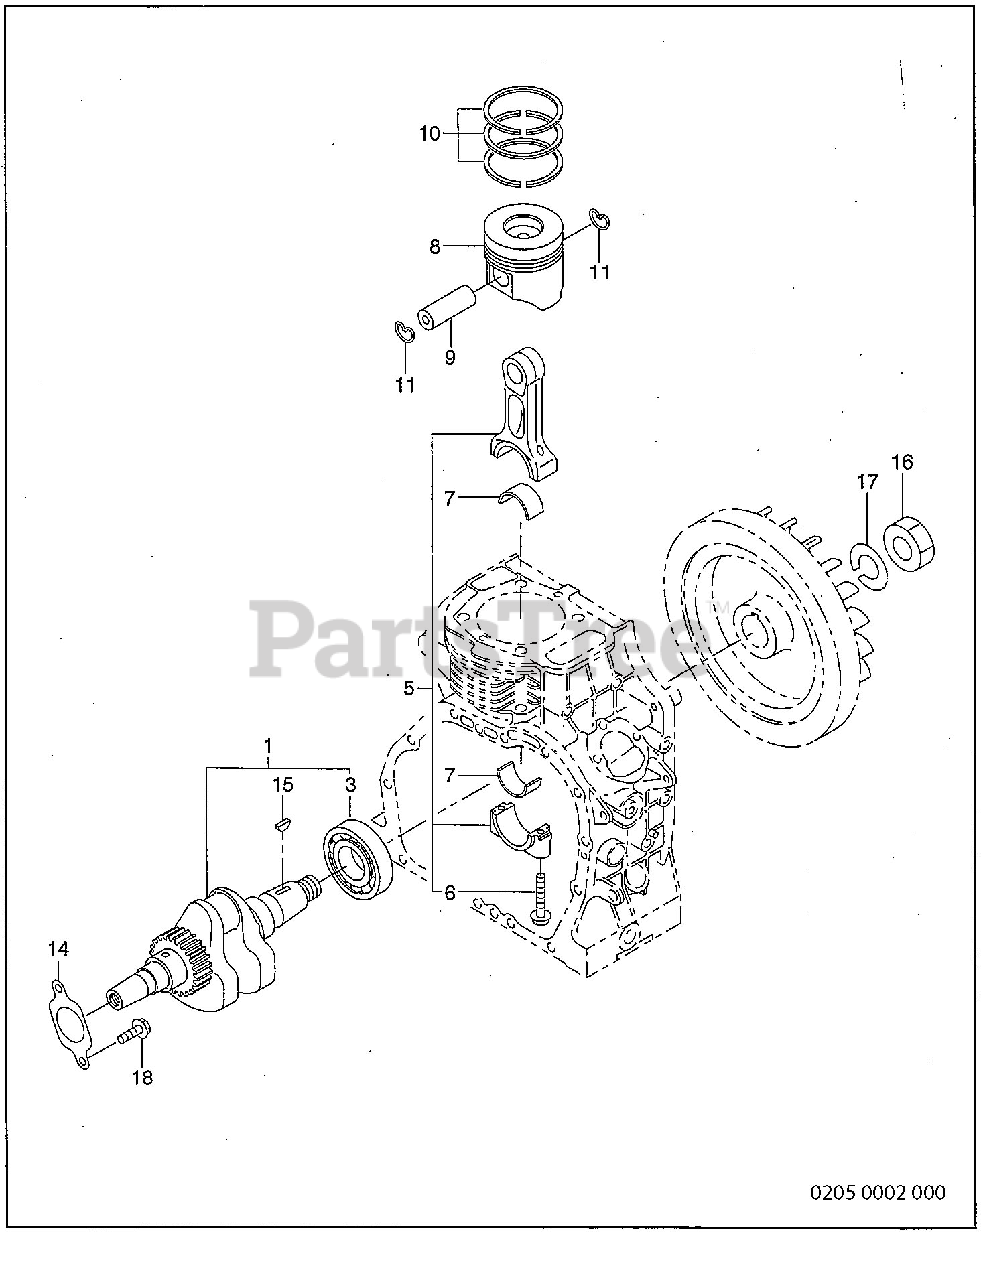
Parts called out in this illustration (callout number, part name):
1	CRANKSHAFT ASSY
5	CONNECTING ROD ASSY
6	CONNECTING ROD BOLT
7	LARGE END BEARING, STD.
7	LARGE END BEARING, under size 0.25mm
7	LARGE END BEARING, under size 0.50mm ·
8	PISTON, over size 0.25mm
8	PISTON, over size 0.50mm
10	PISTON RING SET, STD.
10	PISTON RING SET, over size 0.25mm
10	PISTON RING SET, over size 0.50mm
14	THRUST WASHER (t=0.8)
14	THRUST WASHER (t=1.0)
14	THRUST WASHER (t=1.2)
